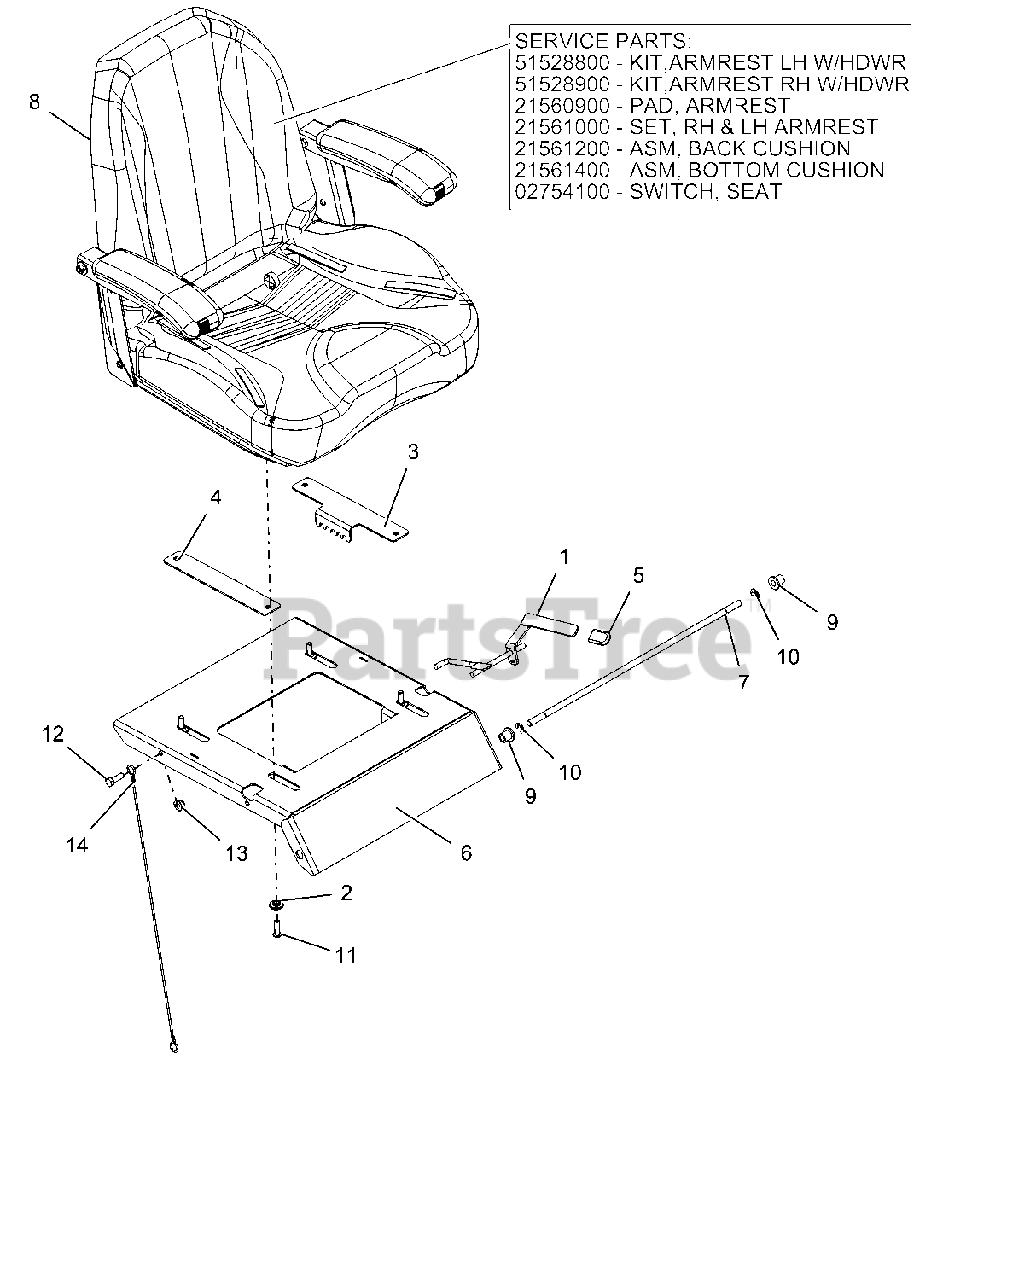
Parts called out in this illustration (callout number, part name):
1	WLDMT, ADJUSTABLE SEAT LATCH
2	BSHG, FLG .325X.499X.26X.88
3	PLATE, ADJUSTABLE SEAT TRACK
4	PLATE, ADJUSTABLE SEAT SLIDE
5	GRIP, SEAT LEVER, GREY
6	PLATE, SEAT
7	ROD, SEAT PIVOT
8	SWITCH- SNAP MTG N.O.
8	KIT, ARMREST LH
8	KIT, ARMREST RH
8	SEAT, GREY
8	PAD, ARMREST (HARD)
8	SET,RH & LH ARMREST -HARD
8	ASM,BACK CUSHION-ARIENS X
8	ASM,BOTTOM CUSHION-ARIENS X
9	BSHG-FLG .38X.580X.667X.750
10	RG-RTNG-EXT .375X.035 TYP E
11	SCR-SKH .31-18X1.0 BTNHD YWZC
12	@BLT-HEX .31-18X1.00 GR5 YWZC
13	@NUT-LK-NYL-FLG .31-18 YWZC
14	LANYARD, SEAT CABLE .093X19.5
